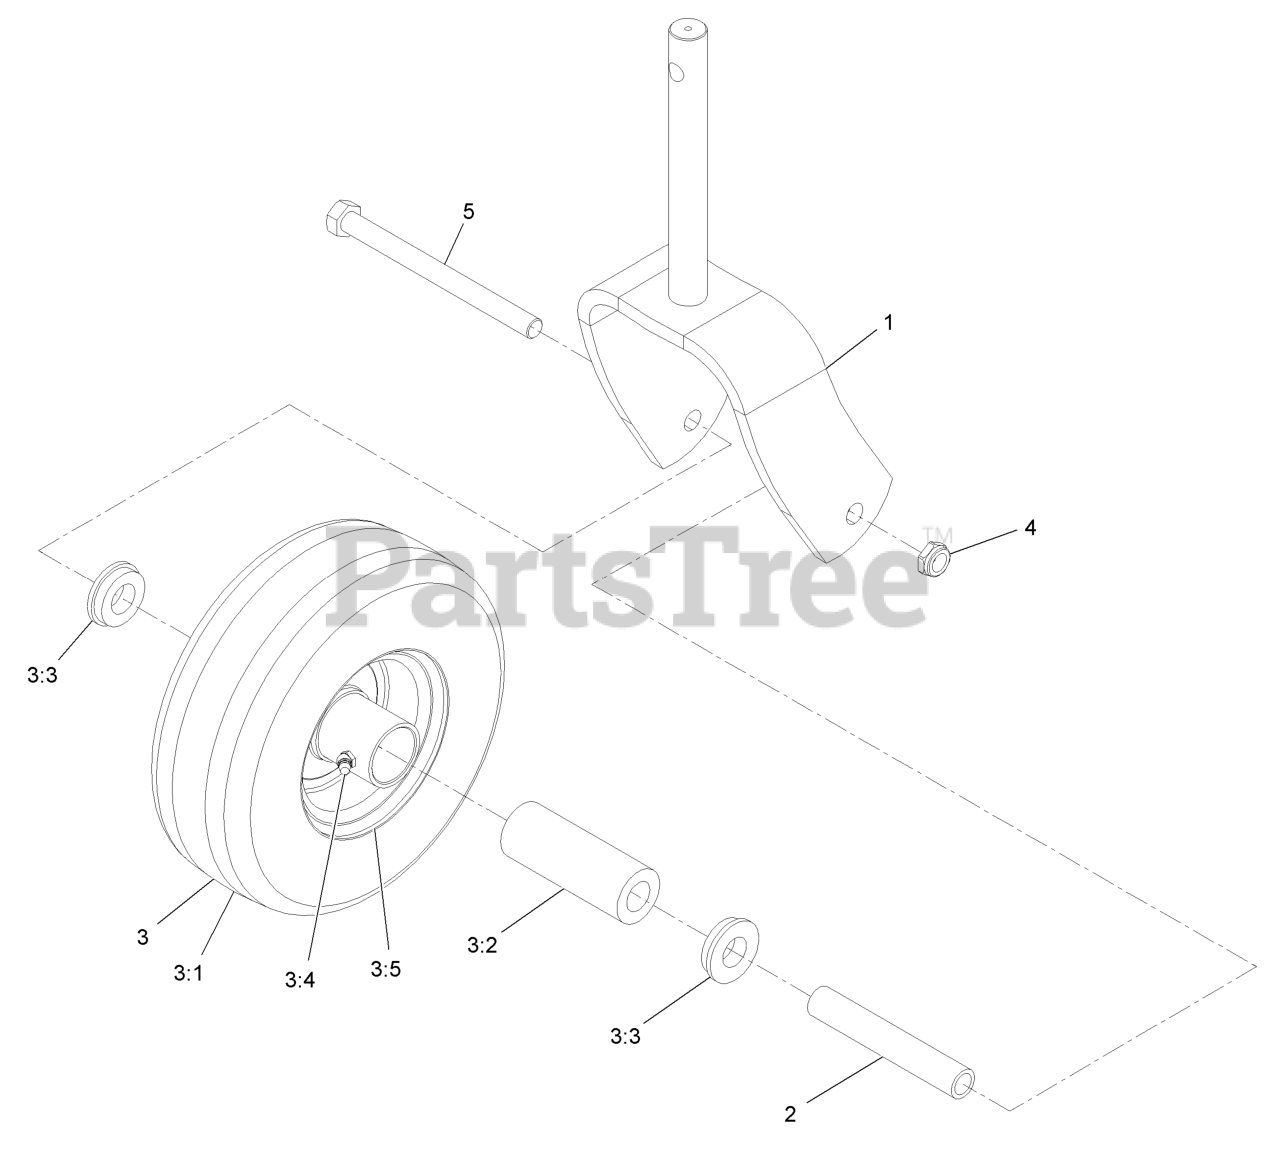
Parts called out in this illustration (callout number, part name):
1	FORK-CASTER
3	WHEEL AND TIRE ASM
3:1	Tire
3:2	BEARING
3:3	BUSHING
3:4	FITTING-GREASE
3:5	Wheel
4	NUT-HEX
5	SCREW-HH
